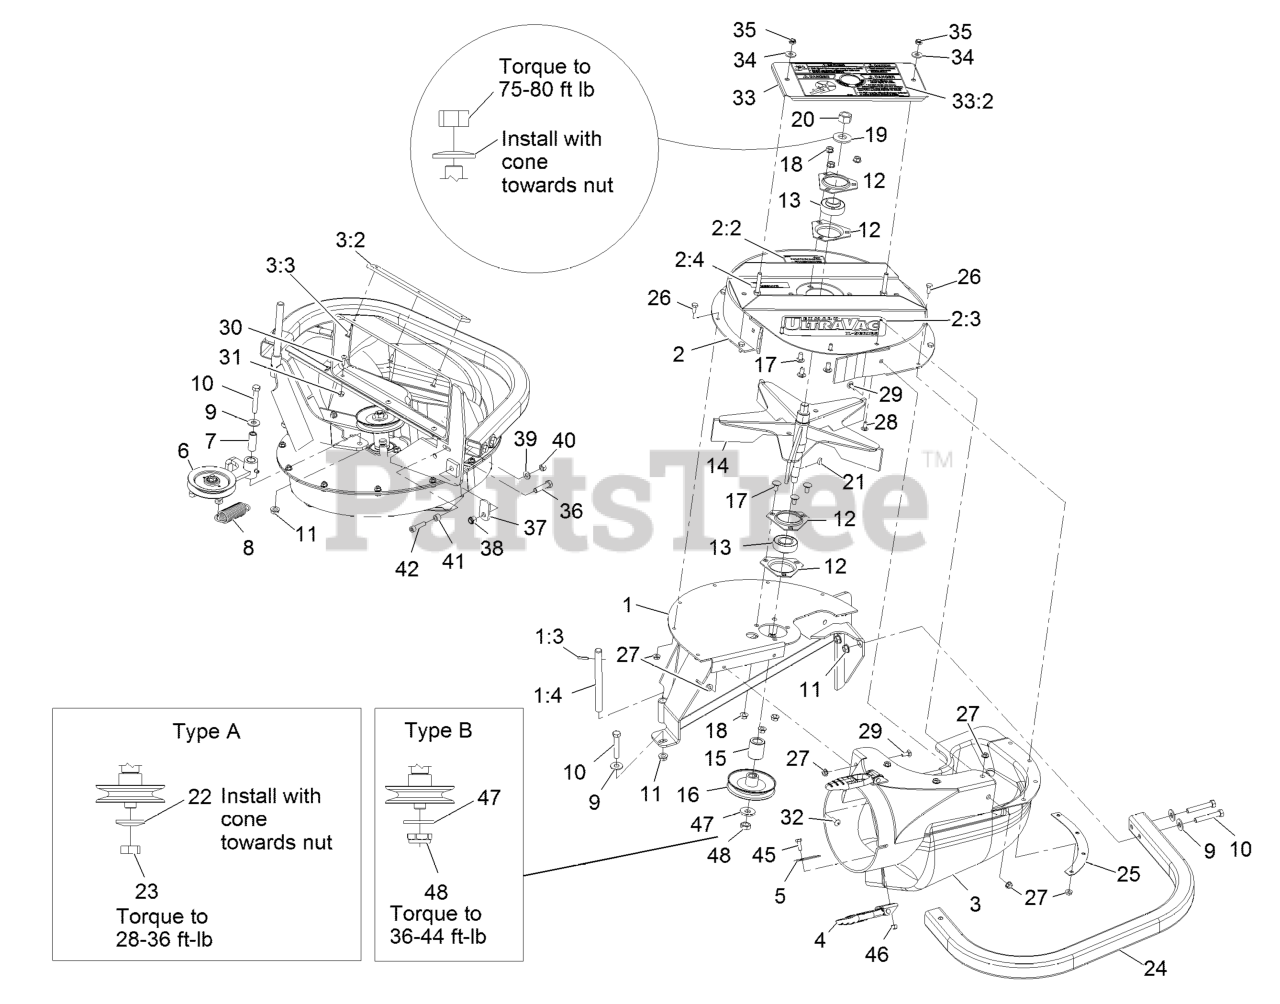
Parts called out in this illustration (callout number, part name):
1	WLD,FRAME LG BLOWER
1:3	PIN-ROLL
1:4	SHAFT-CATCHER, GRASS
2	ASM-UPPER HOUSING LARGE
2:2	DECAL,WEIGHT
2:3	DECAL-ULTRA VAC X-SERIES
2:4	DECAL-COVER, MISSING
3	ASM,BLOWER CHUTE LZ
3:2	PLATE,REINFORCEMENT LARGE
3:3	RIVET-BLIND
4	LATCH-RUBBER
5	PLATE-BACKING
6	Asm, Idler
7	BUSHING
8	SPRING-IDLER
9	WASHER-FLAT
10	SCREW-HH
11	NUT-HHF, WHIZ
12	HOUSING-FLANGE
13	BEARING
14	IMPELLER
16	SHEAVE
17	SCREW-CARR
19	WASHER-SPRING
20	NUT-HEX
21	KEY-WOODRUFF
22	WASHER-SPRING
23	NUT-JAM
25	PLATE-BACKING, BLOWER
26	SCREW-HH
28	SCREW-CARR
29	BOLT-CARR
30	SCREW-HEAD, TRUSS
33	COVER, BEARING
33	ASM, BEARING COVER
33:2	DECAL-WARNING, BLOWER
34	WASHER-FLAT
35	NUT-LOCK, NI
36	SCREW-HH
37	LATCH-CATCHER, GRASS
38	NUT-LOCK, NI
39	WASHER-SPRING
40	NUT-HEX
41	BUSHING, LOCATOR
42	SCREW-HSH
45	SCREW-HH
46	NUT-LOCK, NI
47	WASHER-FLAT
48	NUT-LOCK, NI
